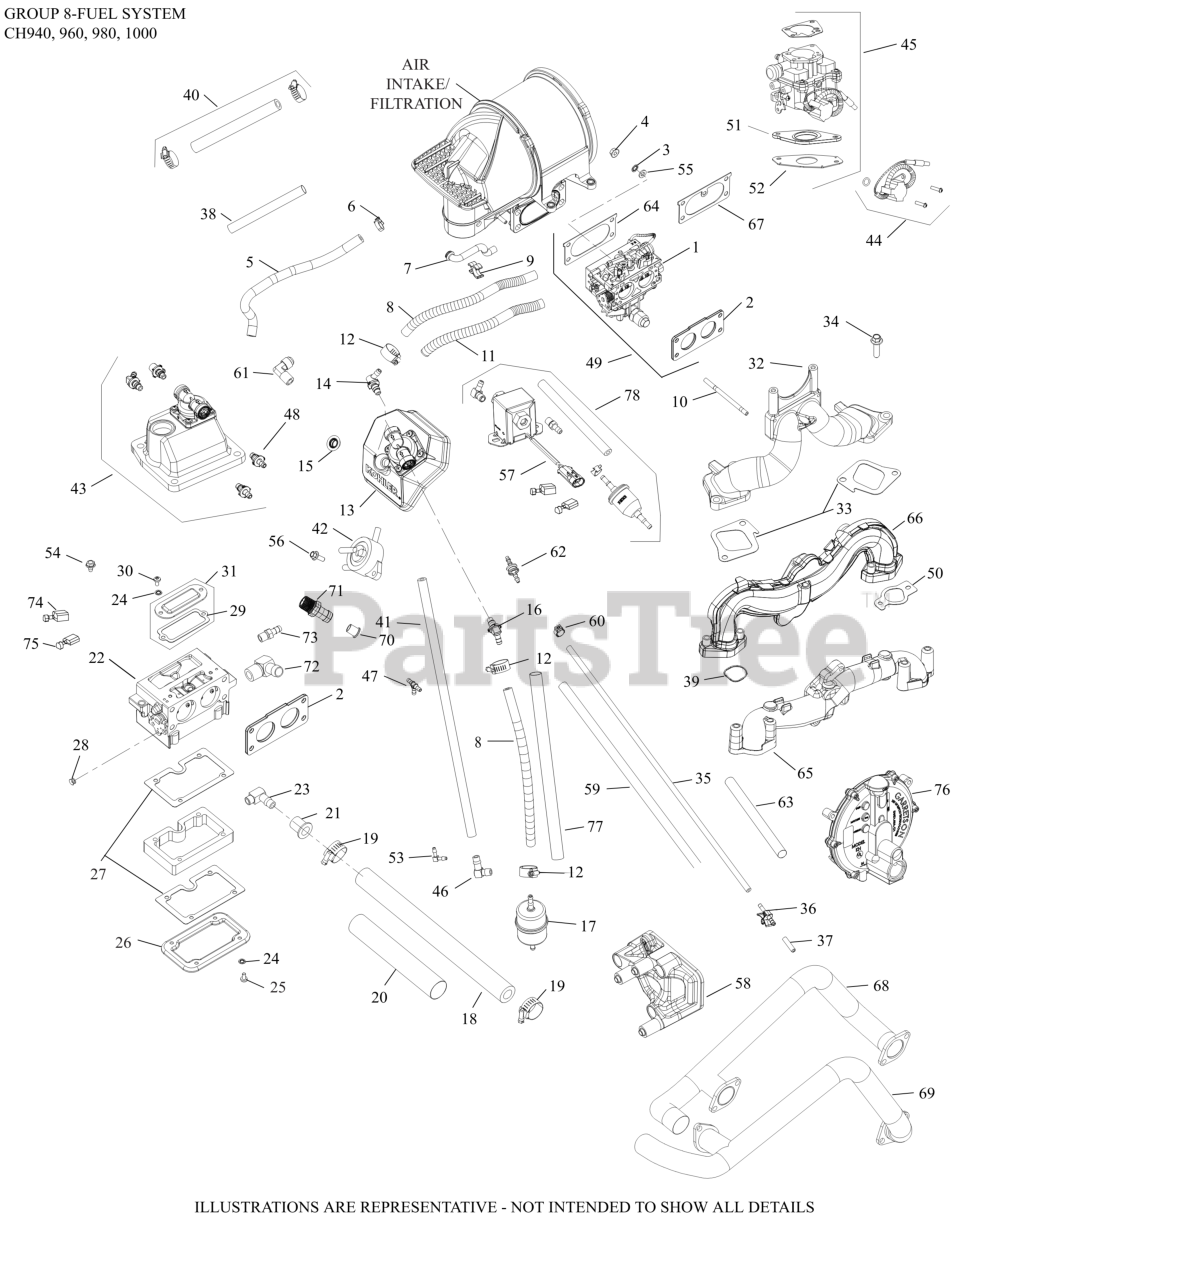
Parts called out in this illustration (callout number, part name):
1	KIT,CARB (KEIHIN)
2	GASKET, CARBURETOR
4	NUT, FLG M6X1.0
10	STUD
18	LINE, LP FUEL
19	CLAMP, HOSE-USE 25 237 32-S
20	SLEEVE,ANTI-ABRASION 203MM INST.
23	FITTING, FUEL
33	GASKET, INTAKE MANIFOLD
34	SCREW, FLG M8X1.25X30
46	CONNECTOR, HOSE
